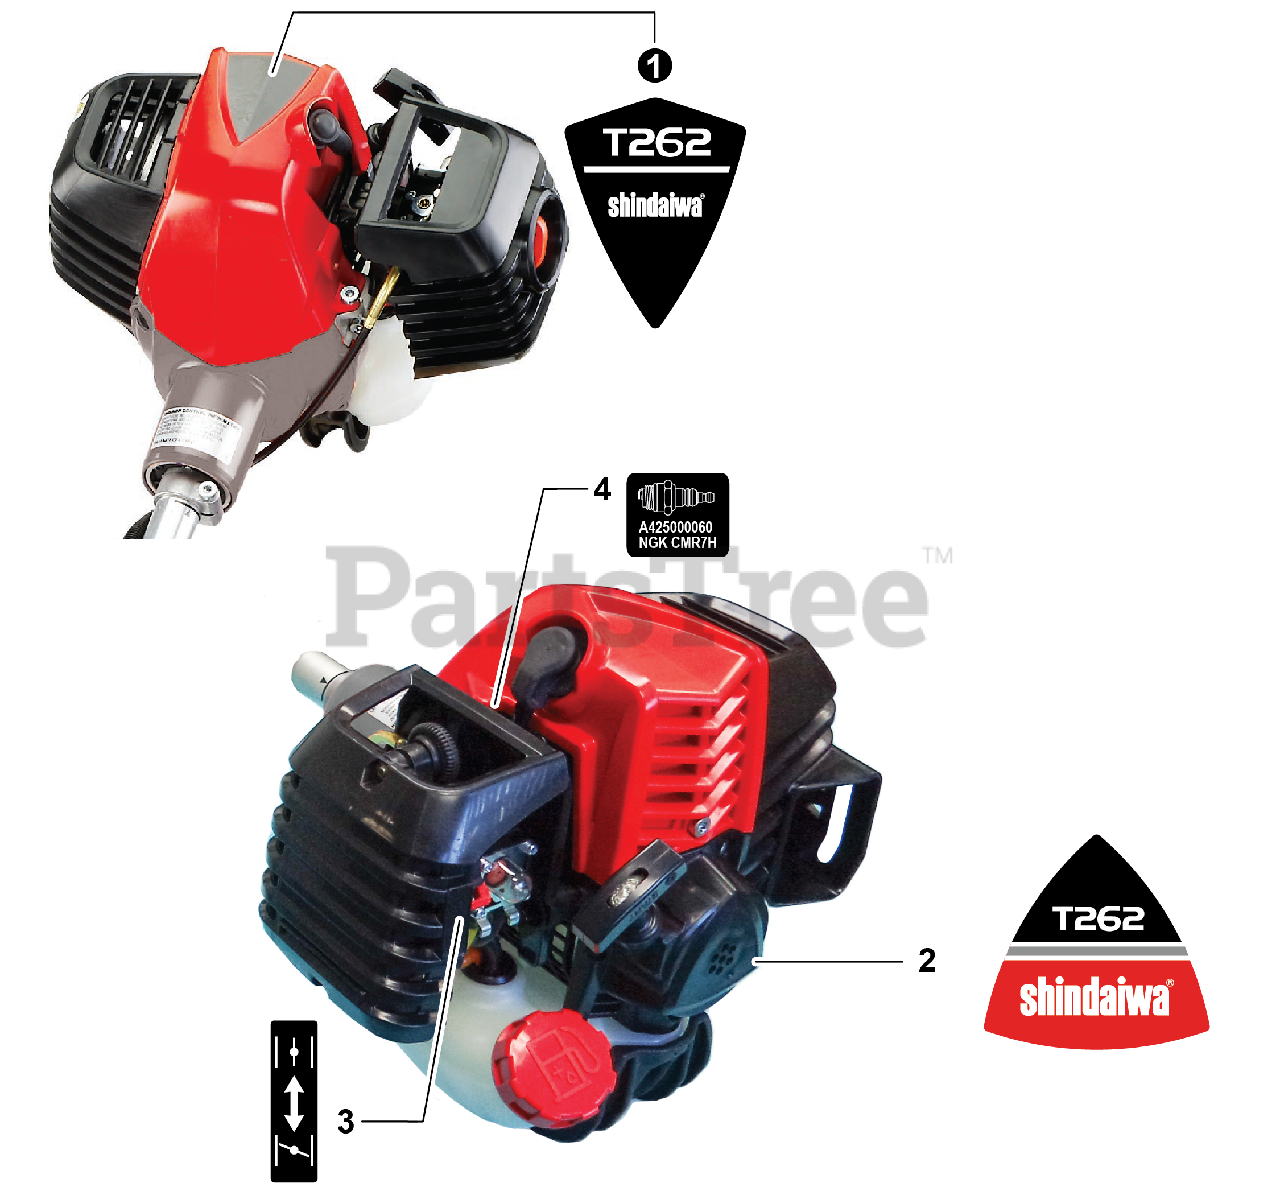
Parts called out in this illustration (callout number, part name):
1	LABEL - MODEL T262
2	LABEL, RECOIL STARTER
3	LABEL, CHOKE
4	LABEL, SPARK PLUG - CMR7H
